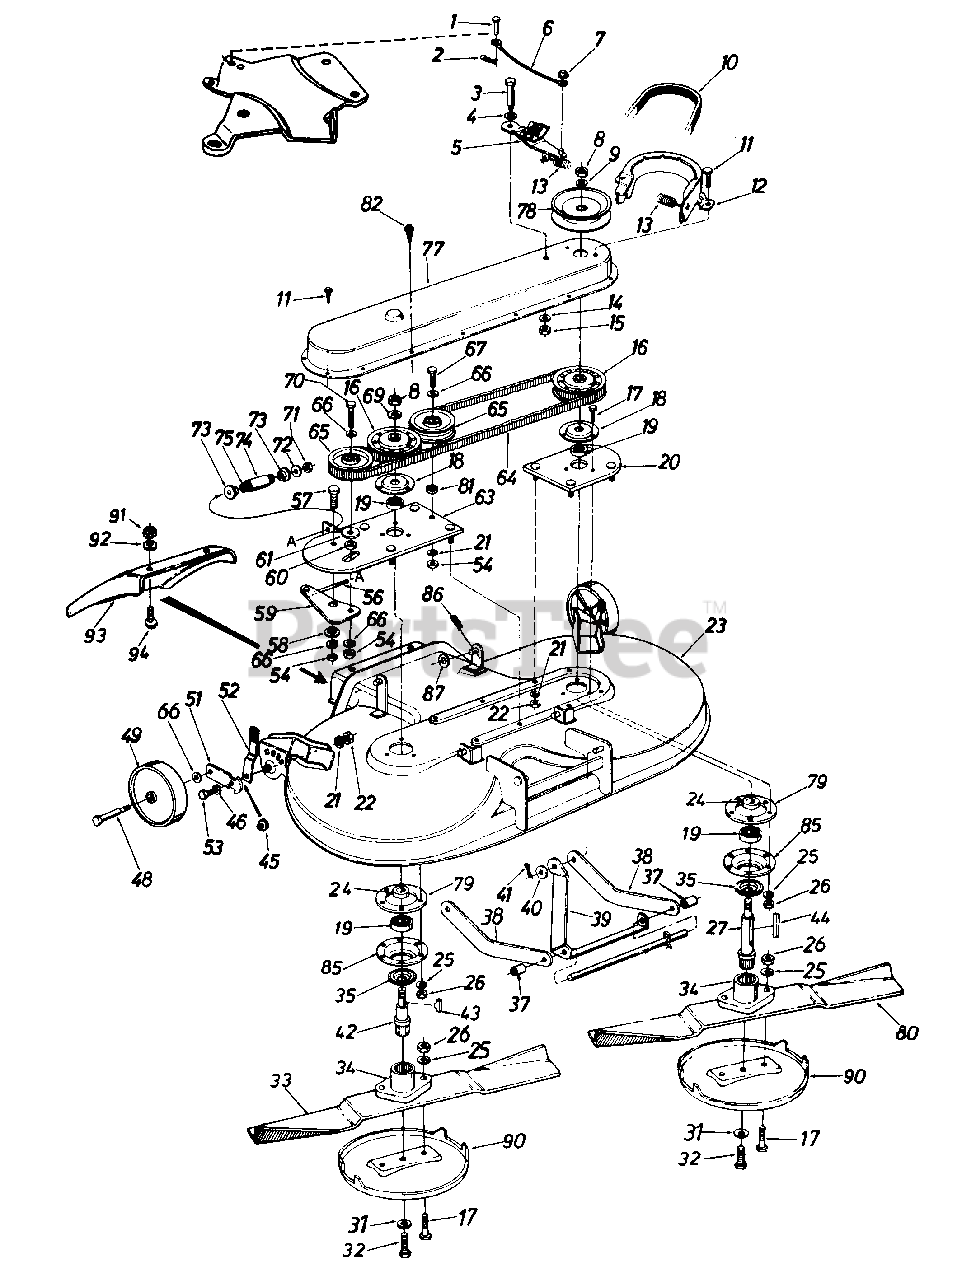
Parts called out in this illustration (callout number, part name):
1	Clevis Pin 1/4" Dia. x 1/2" Lg.
2	Hairpin Cotter 1/4" Dia.
3	Shld. Bolt .437" Dia. x .18" Lg. (5/1 6-1 8)
4	Wave Wash. 7/16" I.D.
5	Spindle Brake Arm Ass'y.
6	Brake Cable Ass'y.
7	Push Cap 1/4"
8	Hex Jam Nut 5/8-18 Thd.
9	Bell-Wash. 5/8" I.D. x 1.25"O.D.
10	"V"-Belt
11	Hex Wash. Hd. Self-Tap Scr. 1/4-20 x .50" Lg.
12	Belt Guard
13	Extension Spring
14	Bell-Wash..34" I.D.
15	Hex L-Nut 5/16-18 Thd.
16	Sprocket Pulley Ass'y.
17	Hex Bolt 5/16-24 x 1.0" Lg. (Grade 5)
18	Bearing Housing
19	Ball Bearing .787" I.D. x 1.85"O.D.
20	Spindle Plate Ass'y.
21	L-Wash. 3/8" I.D.
22	Hex Jam Nut 3/8-24 Thd.
23	44" R.D. Deck Ass'y.
24	Spacer
25	L-Wash. 5/16" I.D.
26	Hex Nut 5/16-24 Thd.
27	Blade Spindle L.H.
31	L-Wash. 3/8" I.D. H.D.
32	Hex Lock Bolt 3/8-24 x .88" Lg.
33	22.5" Blade L.H. Rotation
34	Blade Adapter
35	Bearing Shield
37	Spacer 5/8" I.D. x 7/8" O.D.
41	Cotter Pin 3132" Dia. x 1.00" Lg.*
42	Blade Spindle R.H.
43	Sq. Key 3/16" x .75" Lg.
44	Sq. Key 3/16" x 1.50" Lg.
45	Shoulder Spacer
46	Bell-Wash. .400" I.D.
48	Shld. Bolt 3/8-16 x 1.41" Lg.
49	Wheel Ass'y. Comp. 6" x 1.38"
51	Wheel Pivot Bar
52	Spring Lever Ass'y. w/Knob
53	Hex Bolt 3/8-24 x 1.25" Lg. (Grade 5)
54	Hex Cent. L-Nut 3/8-24 Thd.
56	Adjustment Link 5/16-18 x 4-9/16" Lg.
57	Hex Bolt 3/8-24 x 1.0"
58	Shld. Spacer.625" I.D.
59	Belt Idler Brkt.
60	Spacer .38" I.D. x .625" O.D. x .265
61	Fl-Wash. .38" I.D. x 1.37" O.D. x .1 25
63	Spindle & Idler Mount Plate Ass'y.
64	HTD Twin Power Belt
65	Fl-ldler Pulley 3.50" O.D.
66	Bell-Wash. .38" I.D.
67	Hex Bolt 3/8-24 x 1.75" Lg. (Grade 5)
69	Bell-Wash. 5/8n I.D.
70	Hex Bolt 3/8-24 x 2" Lg.
71	Hex Insert L-Nut 5/16-18 Thd.
72	Fl-Wash. .344n I.D. x 1.125"O.D. x .125
73	Shld. Spacer.625n I.D.
74	Spacer-Adj. Bolt
75	Compression Spring
77	N Belt Cover
78	Deck Drive Pulley
80	22.5" Blade R.H. Rotation
81	Fl-Wash. .88" I.D. x 1.0" O.D.
82	Hex Wash. Hd. Self-Tap Scr. 1/4-20 x .75" Lg.
85	Open Bearing Housing
86	Hairpin Cotter
87	Fl-Wash. 1/2" I.D.
92	L-Wash. 1/4" I.D.
